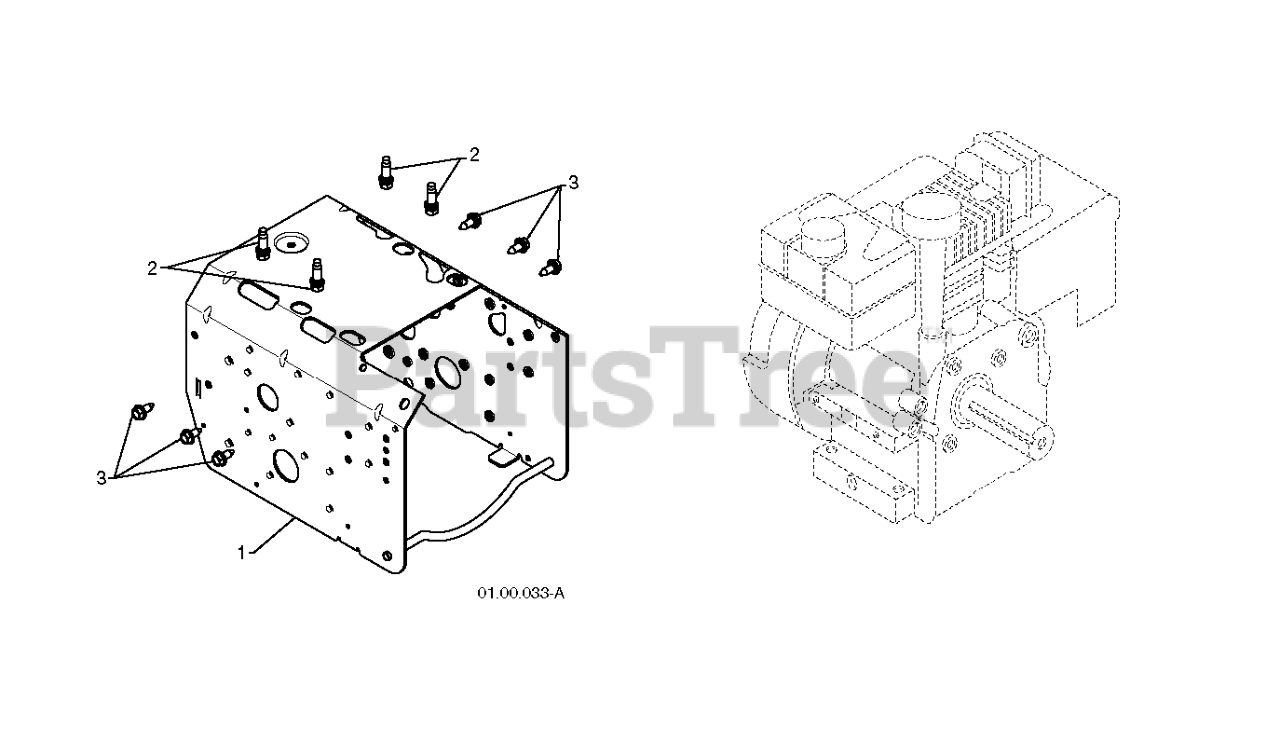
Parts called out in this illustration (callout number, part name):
1	FRAME.WELD.HYDRO.ORANGE
2	BOLT 3/8-16X1-1/8
3	BOLT.HEX.HD.WASHER.5/16-18X.75
